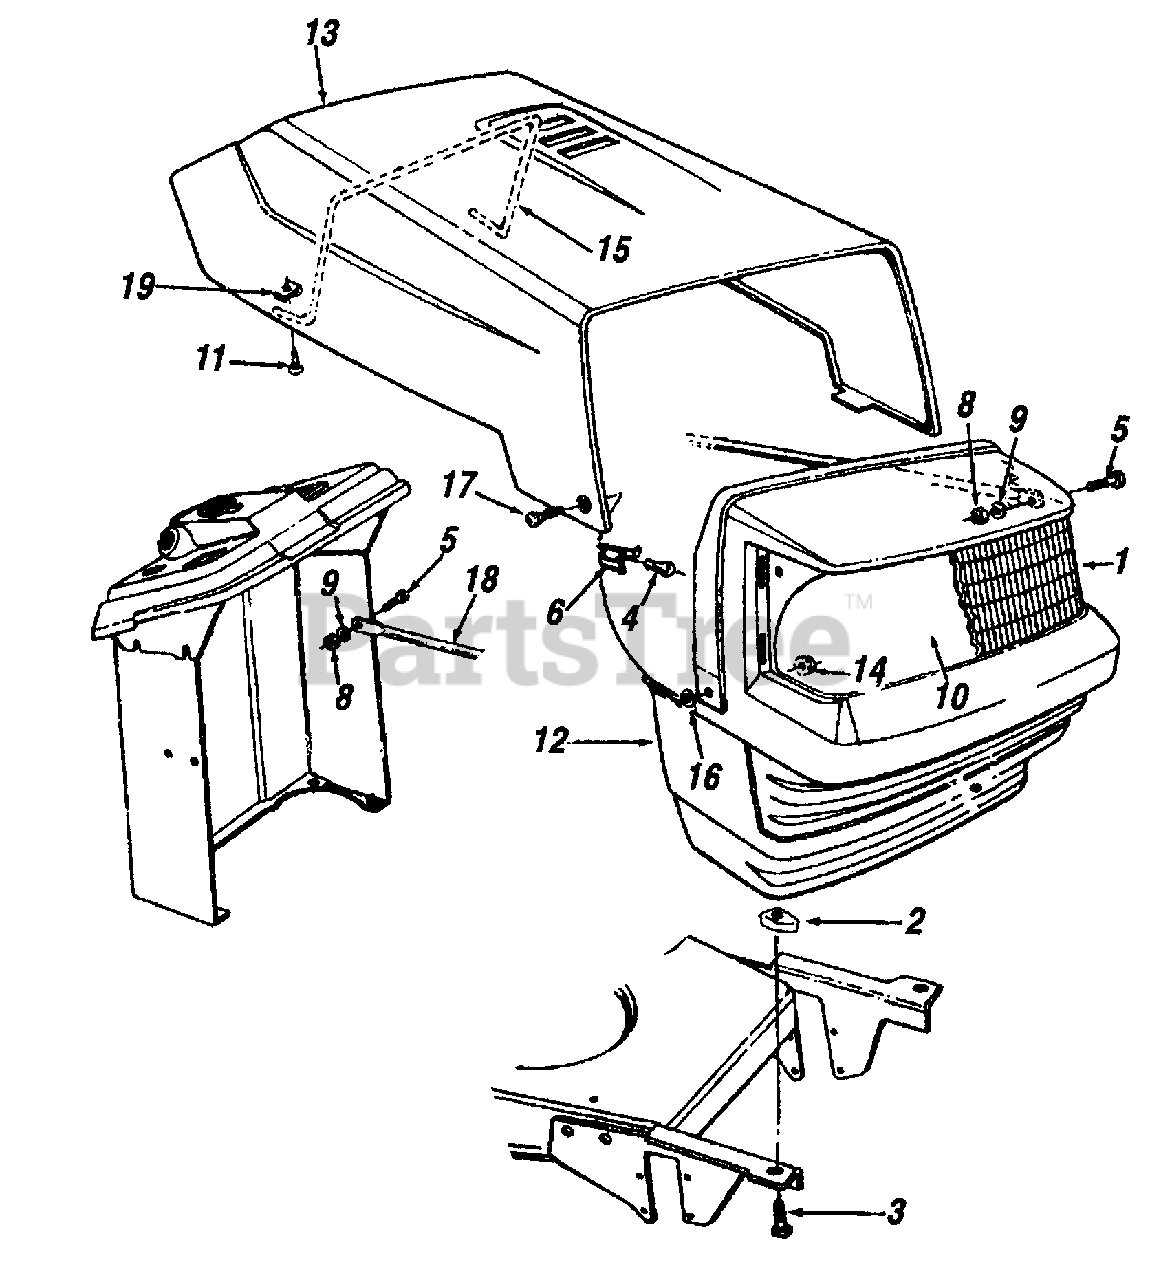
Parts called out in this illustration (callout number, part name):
1	Lens
2	U-Nut 5/16-18 Thd.
3	Hex Bolt 5/16-18 x .75" Lg.
5	Hex Bolt 1/4-20 x .62" Lg.
6	Socket
8	Hex Nut 1/4-20 Thd. Gr.5
9	Lock Washer 1/4" I.D.
10	Grille Reflector Label
11	Hex Tap Screw #10-16 x .75" Lg.
12	Grille
15	Hood Spring
16	Flat Washer .28" I.D. x .75" O.D.
17	Shoulder Bolt
